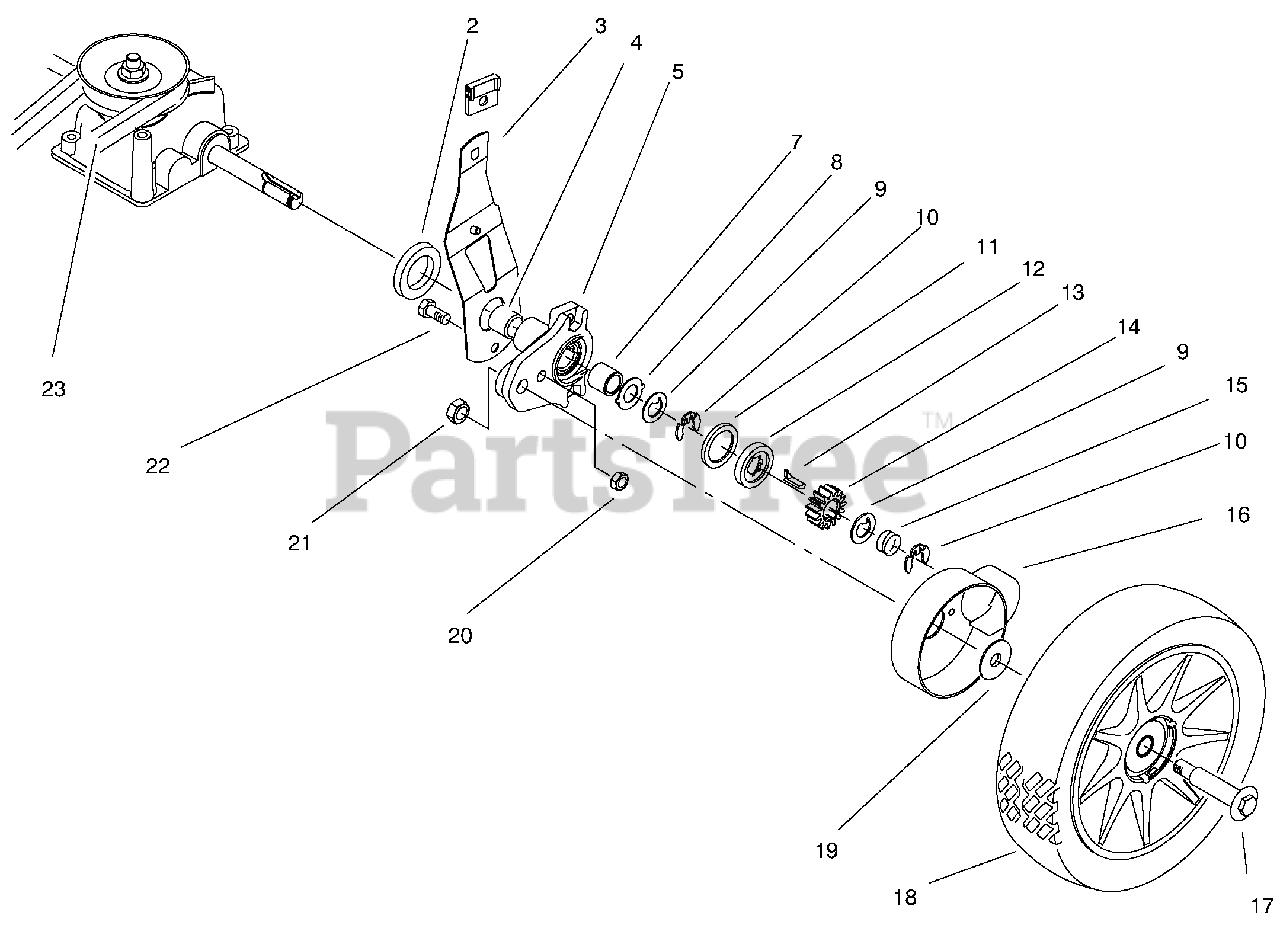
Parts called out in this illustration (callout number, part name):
2	Spacer-Axle Shaft
3	Spring Arm Ass'y
5	Pivot Arm Ass'y-Rear (Incl. Ref.#4, & 7)
8	Washer-Thrust Pivot Arm
9	Washer-Thrust, Keyed
10	Ring-Klip. Special
11	Ring-Friction
12	Washer-Clutch, Plastic
13	Key-Rocking, LH
14	Gear-Pinion
15	Spring-Compression
16	Cover Wheel
17	Bolt-Wheel
18	Wheel Ass'y-8"
19	Washer-Stepped
